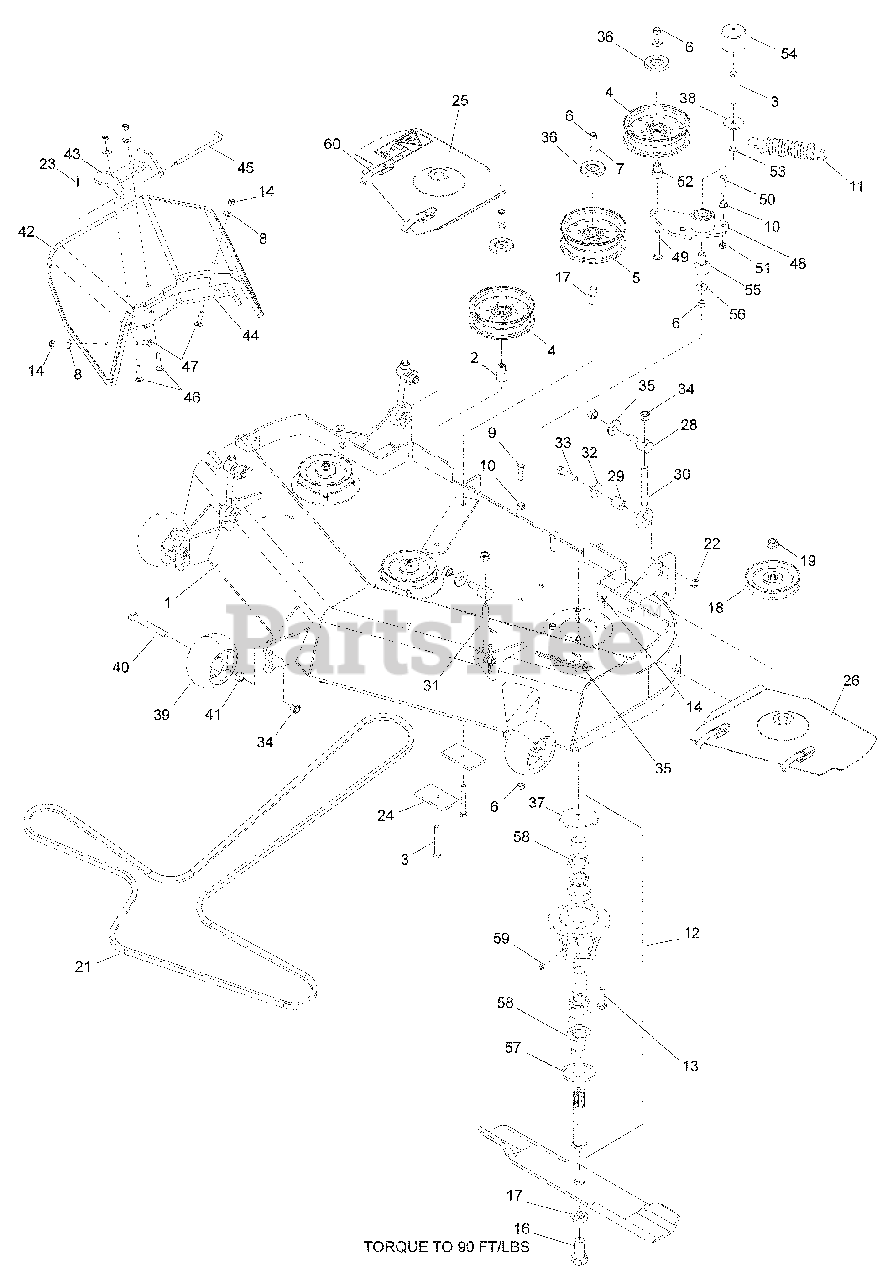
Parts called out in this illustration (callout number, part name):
1	DECK w/DECALS
2	BUSHING, IDLER
3	HCS 3/8-16 x 3
4	PULLEY, IDLER
5	PULLEY, IDLER
6	NUT 3/8-16 HEX NYLOC
7	WASHER 3/8 THICK
8	WASHER 5/16 STD FLT
9	HCS 3/8-16 x 1¼
10	NUT 3/8-16 WHIZLK
11	SPRING, EXTENSION
12	SPINDLE ASSEMBLY
13	HCS 5/16-18 x 1¼
14	NUT 5/16-18 HEX NYLOC
15	BLADE, 16¼
16	HCS 5/8-18 x 1¼
17	WASHER 5/8 SPLIT LOCK
19	NUT ¾-16 FLANGE
20	HCS 7/16-20 x 1½ GR8
21	BELT, DECK
22	NUT 7/16-14 HEX CTRLK GR A
23	PIN, COTTER 1/8 x ¾
24	PAD
25	BELT SHIELD ASSM RT
26	BELT SHIELD ASSM LT
27	DECAL, TUNNEL RAM
31	EYE BOLT ½-13
32	WASHER ½ SPRING
33	HCS 7/16-14 x 1¾
34	NUT ½-13 HEX NYLOC
36	SHIELD, DUST
37	DUST CAP, TOP
38	WASHER 3/8 SPECIAL
39	WHEEL, GAUGE
40	HCS ½-13 x 4
42	CHUTE, DISCHARGE
43	BRACKET, CHUTE
44	REINFORCEMENT, BRKT
45	PIN, CLEVIS
46	RHSNB 5/16-18 x 1½
47	RHSNB 5/16-18 x 1¼
48	ARM, IDLER w/BEARINGS
49	RHSNB 3/8-16 x 2¾
50	HCS 3/8-16 x 1½ GR8
51	NUT 3/8-16 HEX JAM
52	BUSHING, IDLER
53	WASHER 3/8 SAE FLT
54	CAP, VINYL
55	BEARING, PIVOT
56	WASHER 3/8 FLAT STD
57	DUST CAP, BOTTOM
58	SEAL, SHAFTL
59	GREASE POPPET
60	DRAW LATCH
